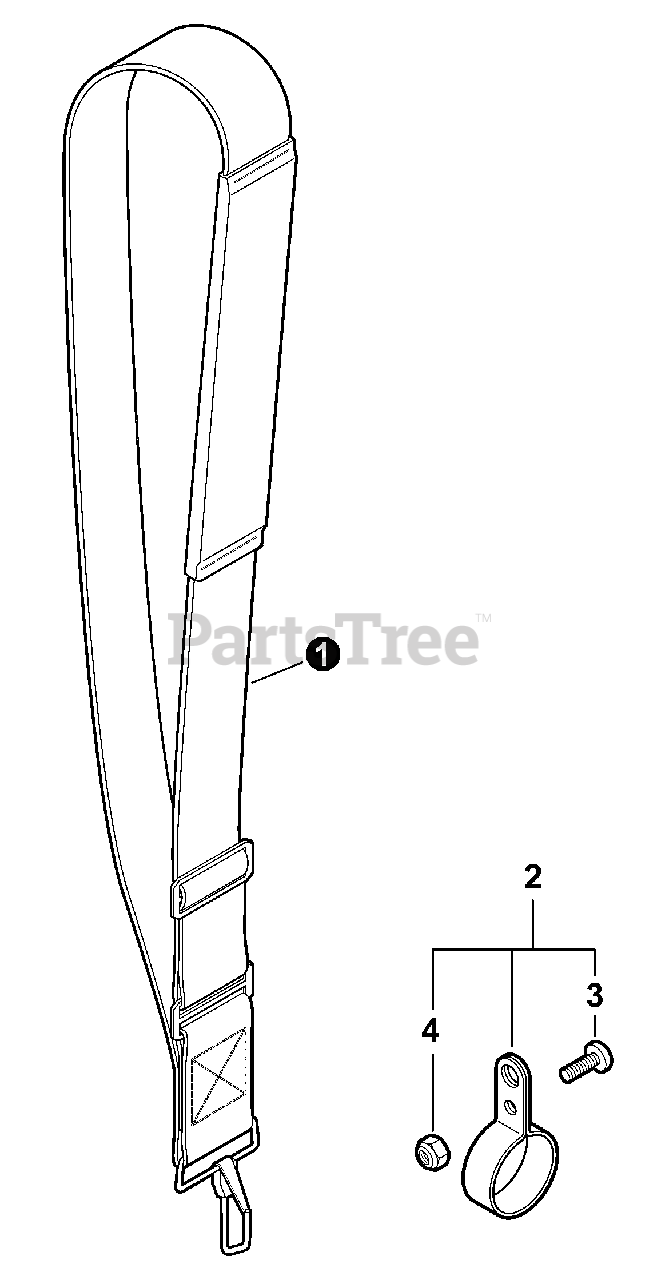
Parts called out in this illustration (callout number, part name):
1	STRAP ASSY, SHOULDER
2	HANGER KIT
3	SCREW 5x10
4	NUT, M5x8 NYLON INSERT
